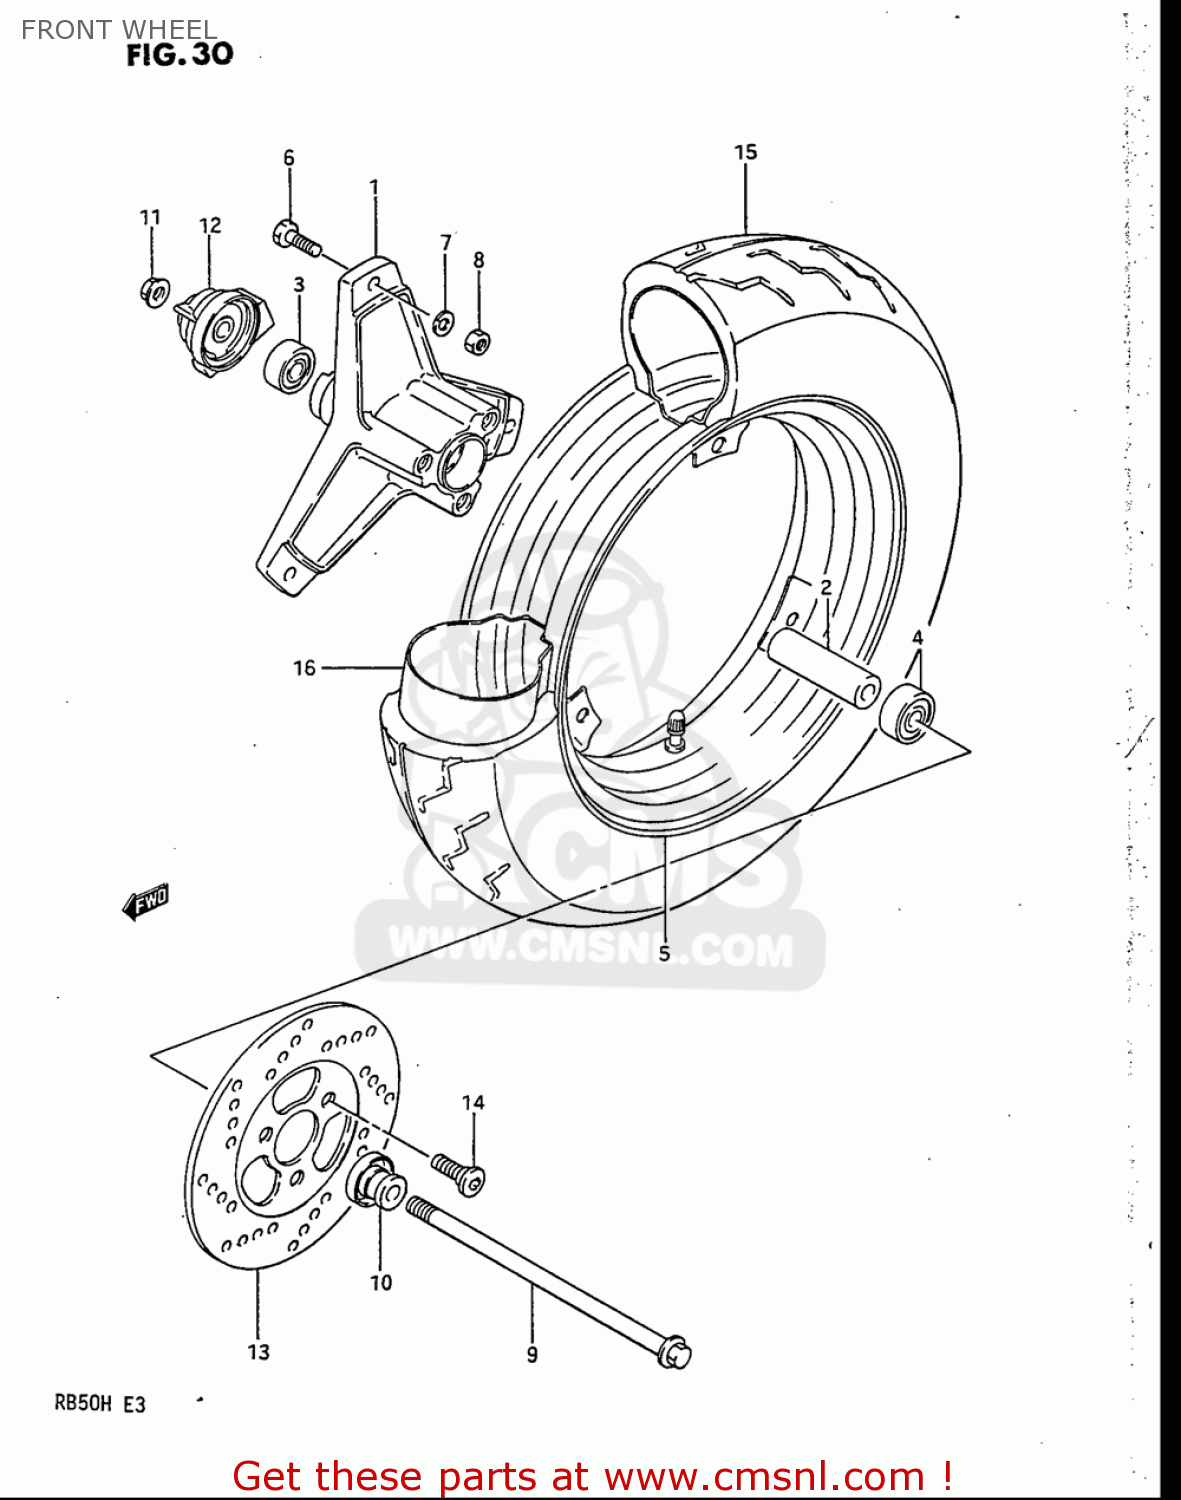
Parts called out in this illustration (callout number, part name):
1	HUB,FRONT WHEEL
3	BEARING
4	BEARING
5	WHEEL,RIM(SILVER)
7	WASHER,LOCK
8	NUT
9	AXLE,FRONT
10	SPACER,FRONT AXLE
11	NUT
12	BOX ASSY,SPEEDOMETER GEAR
13	DISC,FR BRAKE
14	BOLT(8X20)
